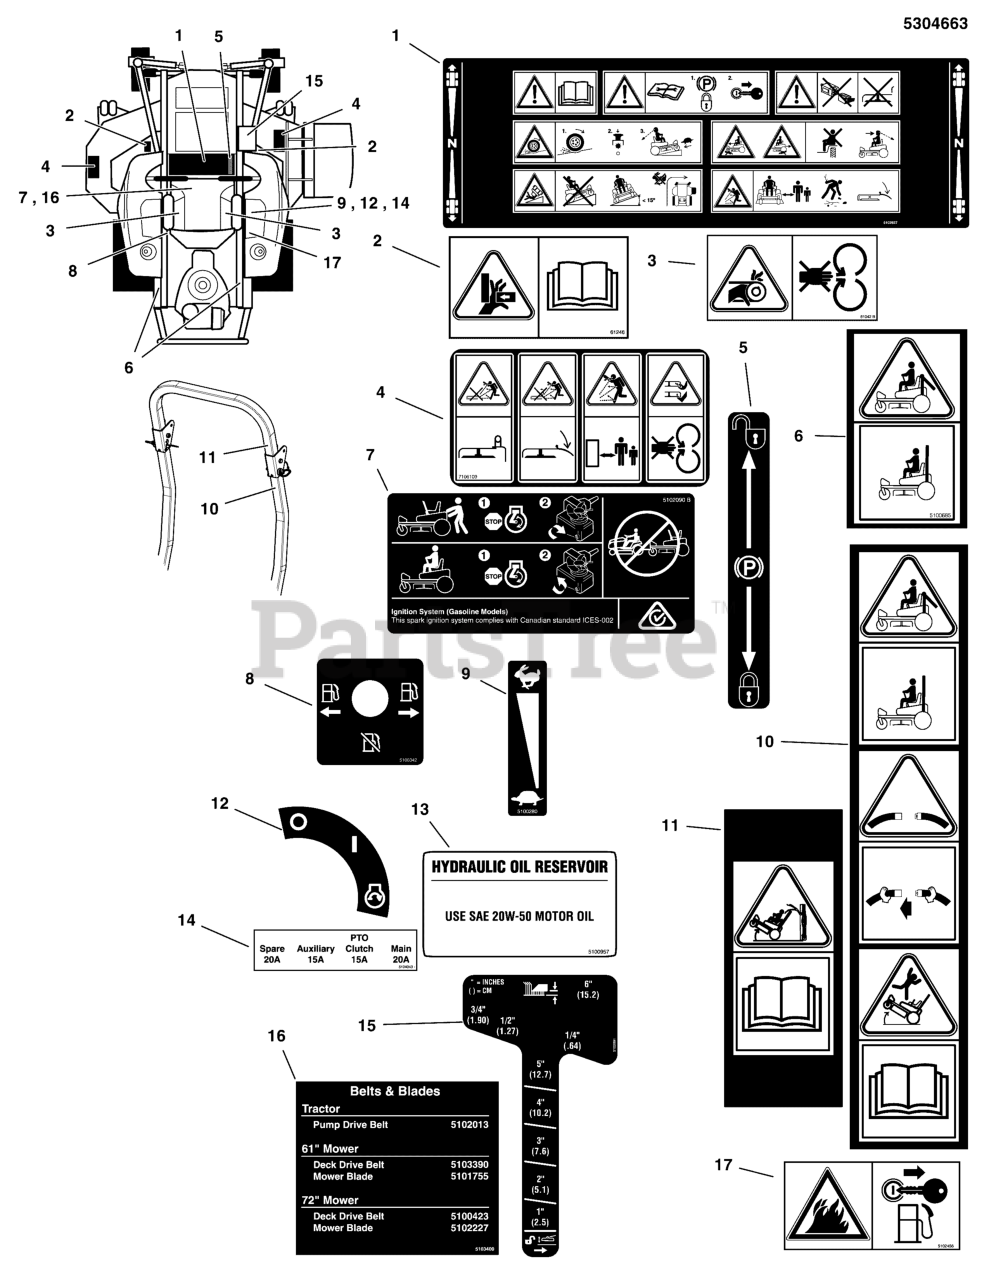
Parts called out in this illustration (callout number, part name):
1	DECAL, MAIN SAFETY, ANSI CE
2	DECAL, PINCH POINT, CE
3	DECAL, CE DANGER
4	DECAL, DISCHARGE SAFETY, EXPORT
5	DECAL, PARKING BRAKE SYMBOLS
6	DECAL, WARNING, ROLL BAR, CE
7	DECAL, TRANSAXLE RELEASE, S200XT
8	DECAL, FUEL VALVE
9	DECAL, THROTTLE CONTROL
10	DECAL, SAFETY, CE ROPS
11	DECAL, SAFETY, CE ROPS, OBS
12	DECAL, IGNITION SWITCH
13	DECAL, HYDRAULIC OIL, 20W50
14	DECAL, FUSE LOCATION, IS2100
15	DECAL, DECK HEIGHT, 1-1/2 TO 6, S200XT
16	DECAL, BELT & BLADE, S200XT
17	DECAL, FIRE ANSI EXPORT
